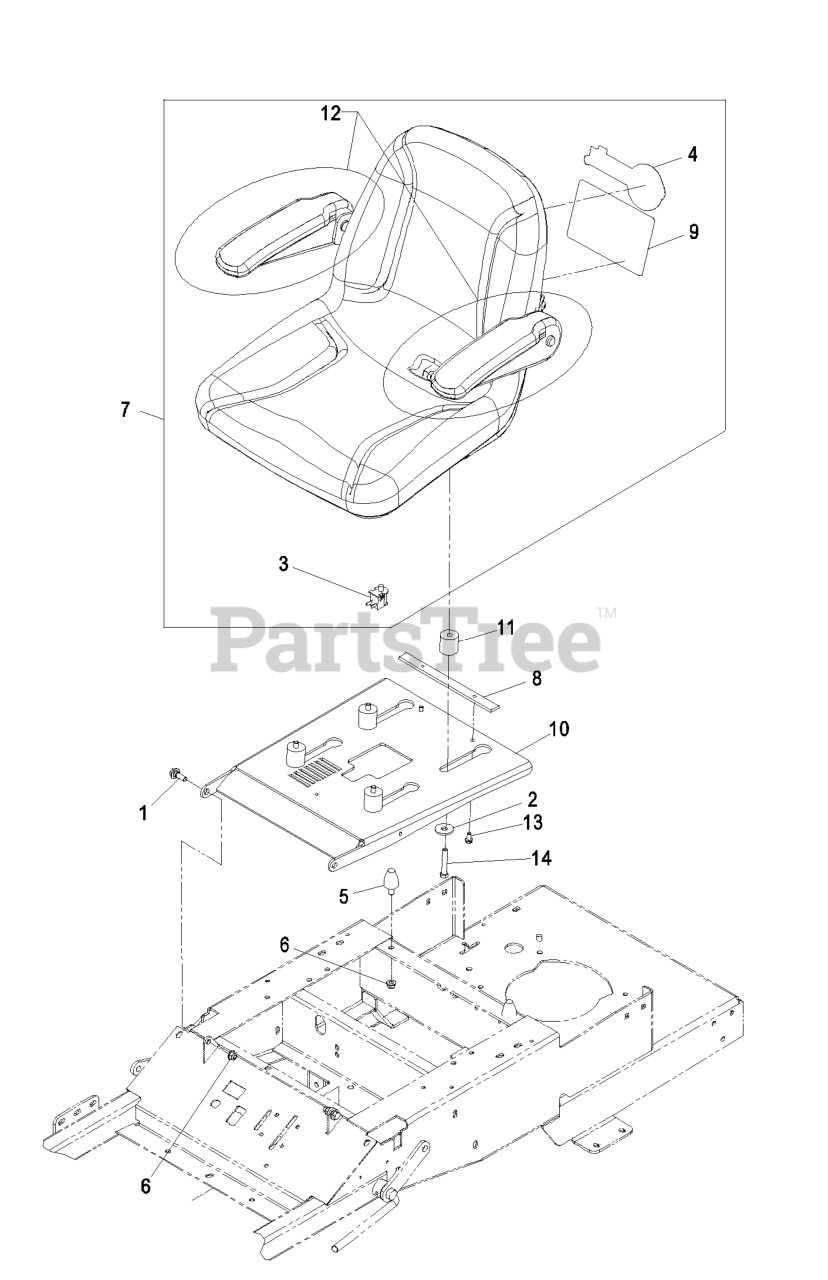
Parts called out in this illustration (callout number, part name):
1	SCREW-SHOULDER
3	SWITCH-BAIL
4	DECAL,EXMARK LOGO
5	BUMPER-SEAT
6	NUT-HF, NI
7	ASM,PHAZER SEAT W/DECALS
8	BAR-STOP, SEAT
10	BRACKET-SEAT
12	ARMREST KIT
13	SCREW-HWH
14	SCREW-HH
